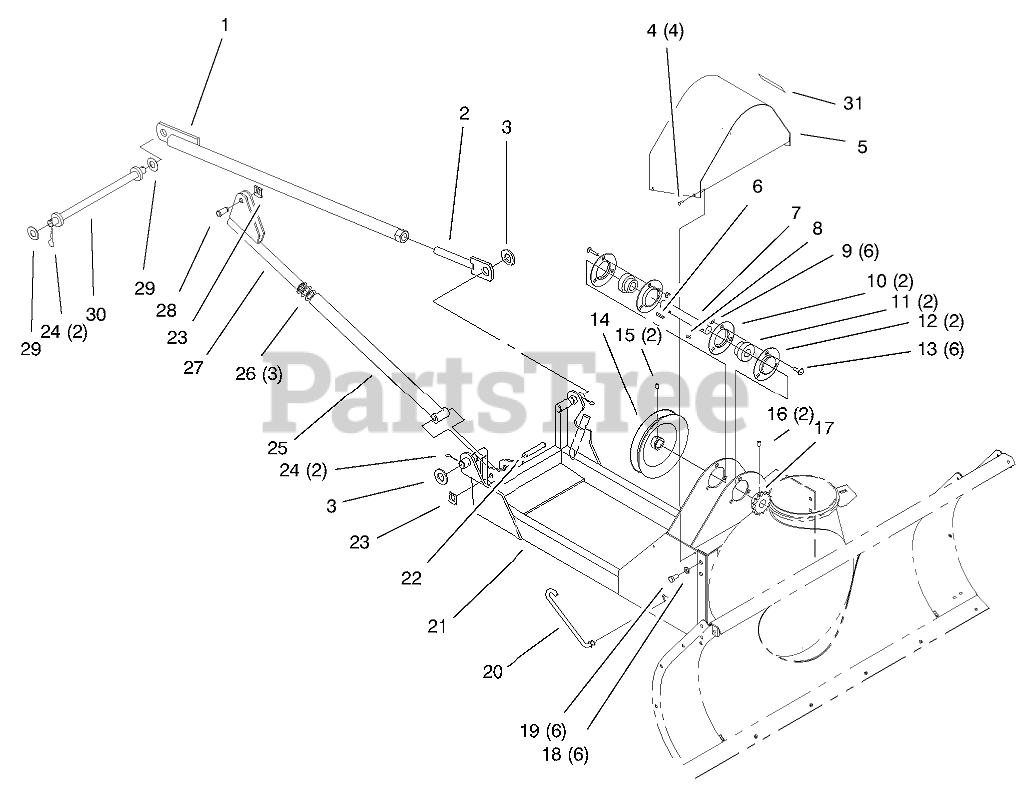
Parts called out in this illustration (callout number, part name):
1	BRACE ASM
2	ADJUSTER ASM
3	WASHER-FLAT
4	SCREW-TAPTITE
5	PULLEY COVER ASM
6	KEY
7	Shaft-Jack
8	KEY-HI PRO
9	NUT-LOCK, NI
10	FLANGE-RELUBE
11	BEARING AND COLLAR
12	Flange
13	BOLT-CARR
14	PULLEY-DRIVE
15	SCREW-SQH
16	SCREW-SET
17	SPROCKET-15 T
18	WASHER-LOCK
19	SCREW-HH
20	LINK-SPRING TENSION
21	FRAME ASM
22	PIN-CLEVIS
23	CLIP-PIN
24	PIN-COTTER, HAIR
25	ROD-LIFT
26	WASHER-FLAT
28	PIN-CLEVIS
29	WASHER-FLAT
30	LINK ASM
31	DECAL-IMPORTANT
